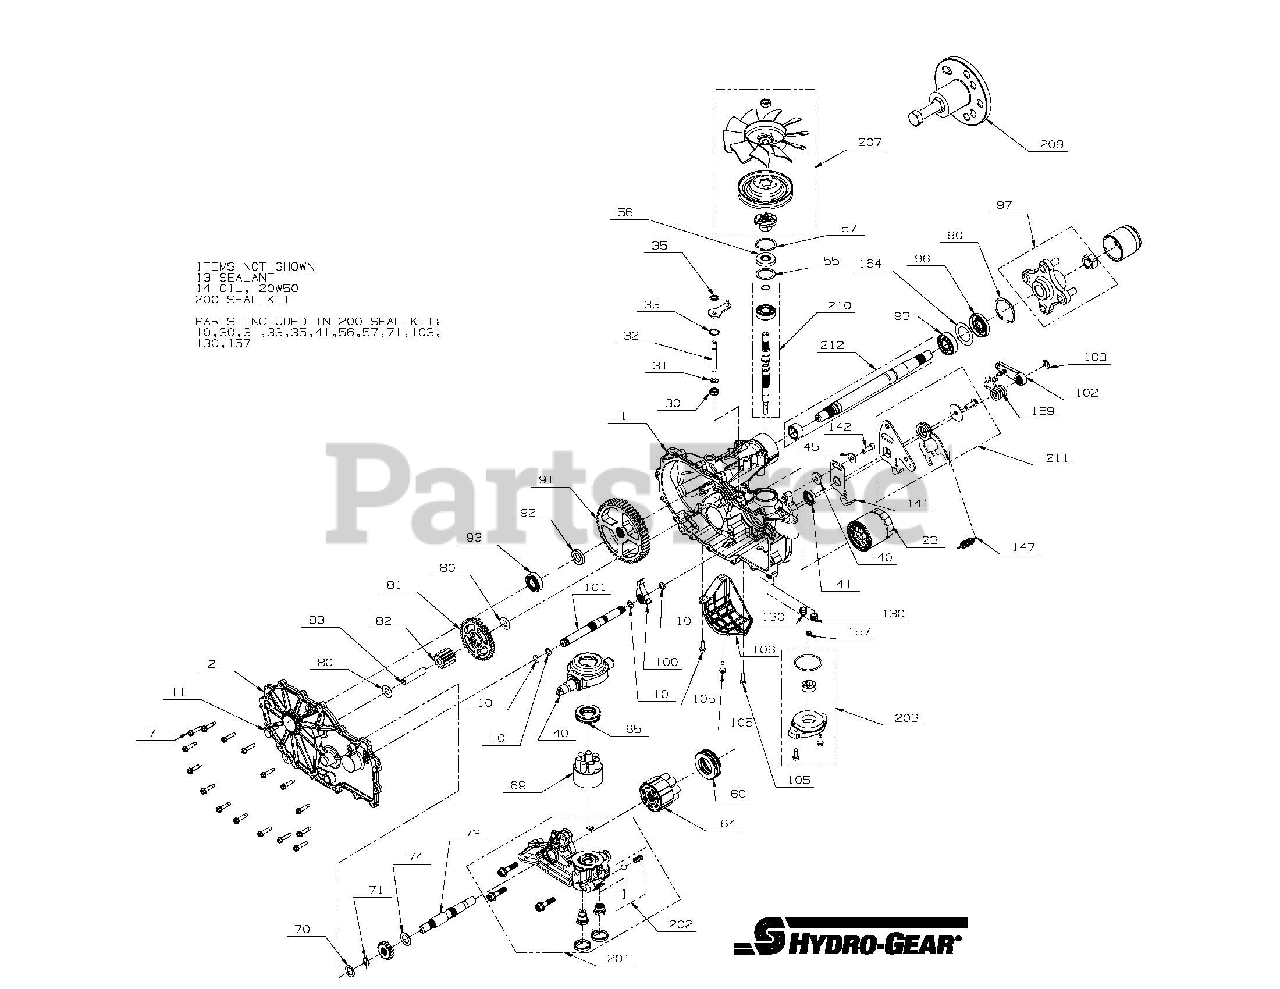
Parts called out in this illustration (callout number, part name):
1	KIT, MAIN HOUSING LH, CHARGE, CONTROL
2	KIT, SIDE COVER LH
7	SCREW,HEX WASHER 1/4-20X1.125
13	SEALANT TUBE 10.1OZ.
23	OIL FILTER, TRANSMISSION
30	SEAL, LIP .375X.75X.25
31	RING. RETAINING
33	RING, RET .750
34	HG BYPASS ARM (52370)
35	RING, RTNG .
40	TRUNNION, SWASHPLATE
41	SEAL, LIP 18X32X7
45	WASHER
55	WASHER 1.23X1.56X.04
56	SEAL, LIP 17X40X7
57	RING, RET 1.56 INT
60	HG THRUST BEARING (51462)
64	HG 16CC CYLINDER BLOCK (71579)
65	BEARING. THRUST 30 X 52 X 13
69	ASSY, BLOCK 7 PISTON
70	WASHER .63X1.0X.05
71	RING, RET 62 EXT
73	SHAFT, MOTOR
74	WASHER .71 X 1.16 X .04
80	WASHER .5X1.0X.032
83	JACK SHAFT (PIN)
90	RING, RETAINING
93	KIT, BEARING
96	SEAL, LIP
97	KIT, HUB 4 BOLT
100	PAWL, BRAKE
101	KIT, BRAKE SHAFT
102	HG ACTUATING KIT HANDLE
105	HFHCS 1/4-20X.75
106	HG FILTER GUARD LH (52247)
130	TUBE, CHARGE TRIPLE O-RING
140	SPACER
141	ARM, NEUTRAL LEFT
142	SHCS 5/16-24X1 PATCH
147	SPRING, HYDROGEAR P/N 51833
157	KIT, GEROTOR SEAL
158	CAP, AXLE
159	SPRING, TORSION
164	WASHER, 1.355 x 2.035 x .021 FLAT
200	KIT, SEAL
201	KIT CENTER SECTION LH CHARGE
202	KIT CHARGE RELIEF
203	KIT, CHARGE PUMP 71411
207	KIT FAN PULLEY
209	HUB PULLER 4 BLT HYDGEAR 71459
210	INPUT SHAFT 2800 HYDGEAR 71442
211	KIT RTN BIDIRECTIONAL
212	KIT SHAFT AXLE
